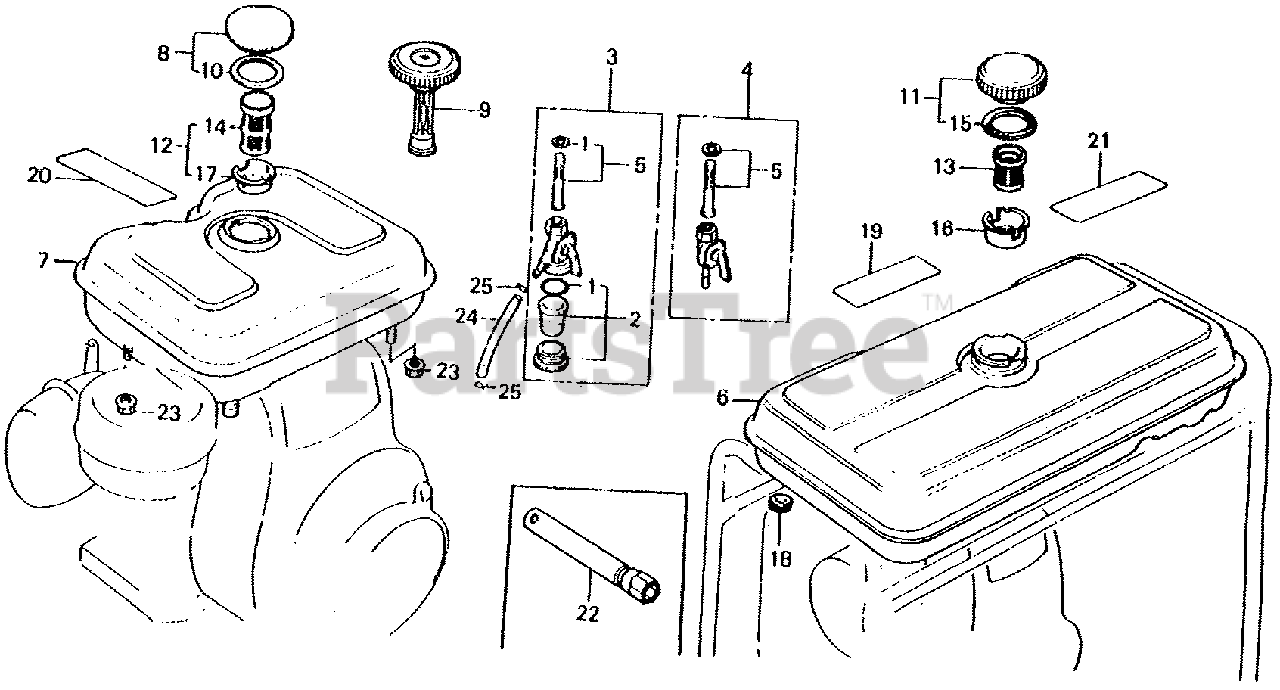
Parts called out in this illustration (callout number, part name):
1	GASKET SET, VALVE
2	CUP SET, FUEL STRAINER
3	PETCOCK ASSY.
5	SCREEN SET
6	TANK, FUEL *NH31* (MCKINLEY WHITE)
6	TANK, FUEL
7	TANK, FUEL *NH31* (MCKINLEY WHITE)
8	CAP, FUEL FILLER
9	GAUGE, FUEL
10	GASKET, FUEL FILLER CAP
11	CAP, FUEL FILLER
11	CAP, FUEL TANK (NOT AVAILABLE)
12	FILTER, FUEL
13	FILTER, FUEL
14	FILTER, FUEL
15	GASKET, FUEL FILLER CAP
15	GASKET, FUEL FILTER (NOT AVAILABLE)
16	HOLDER, FUEL FILTER
17	HOLDER, FUEL FILTER
18	RUBBER, TANK CUSHION
19	MARK A, CAUTION
20	MARK, CAUTION (ENGLISH/FRENCH)(SPANISH)
21	MARK, CAUTION (CO)(ENGLISH/FRENCH)(SPANISH)
22	WRENCH, SPARK PLUG
23	NUT, FLANGE (6MM)
24	BULK HOSE, FUEL (4.5X3000) (4.5X70)
25	CLIP, TUBE (B8)
